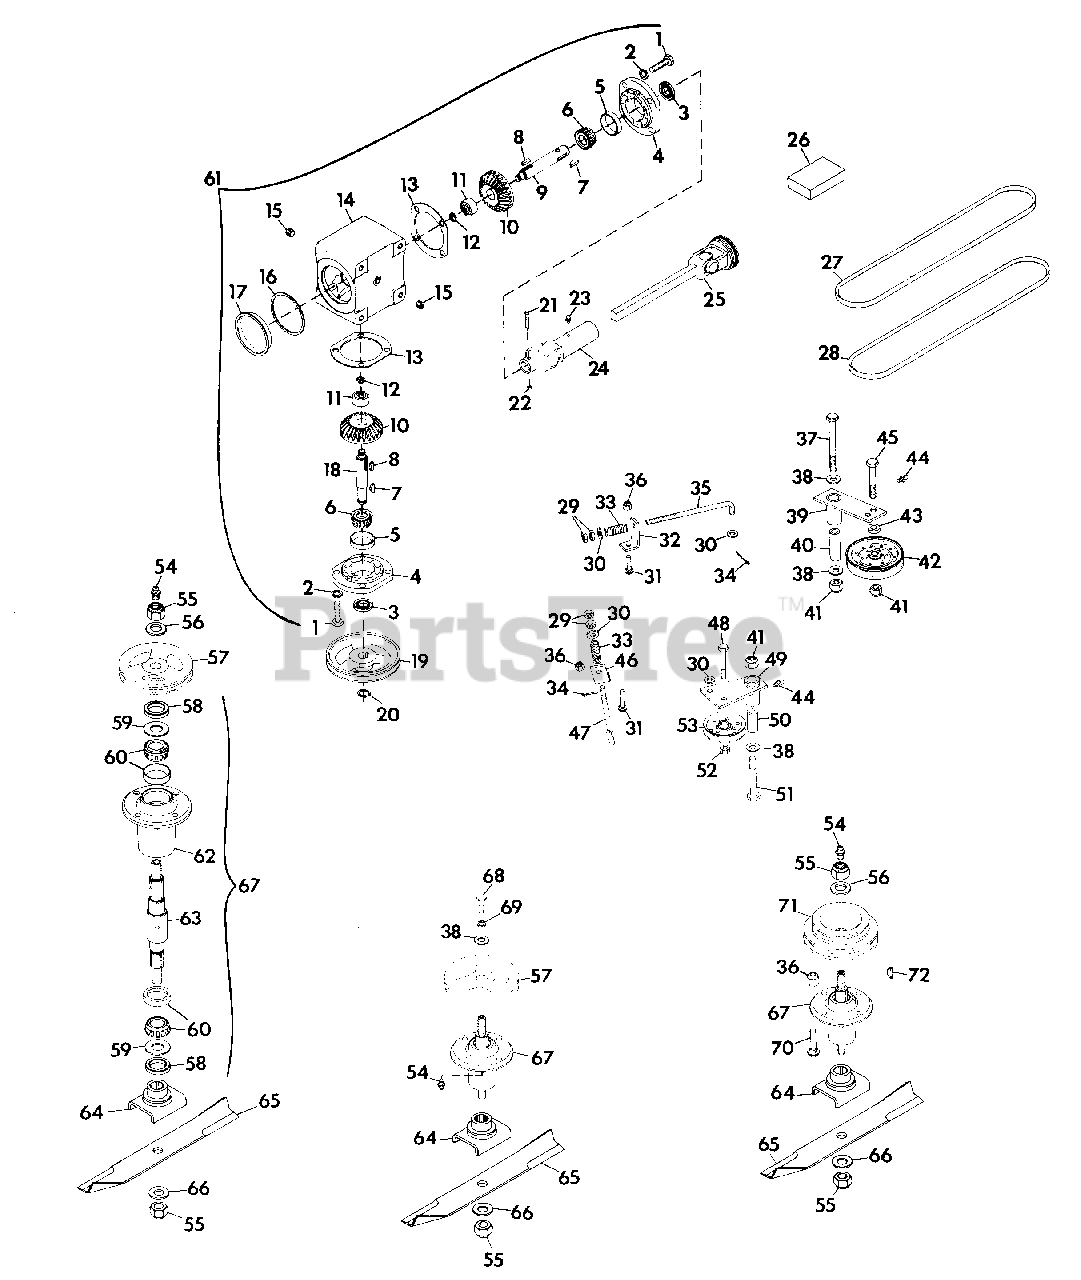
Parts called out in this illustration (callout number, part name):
1	BOLT, HEX 5/16-18X1.00
2	WASHER, LOCK 5/16 REG
3	SEAL
4	COVER
5	CUP, BEARING
6	CONE, BEARING
7	KEY, WOODRUFF .250X.875 HRD #A
8	KEY, SQUARE
9	SHAFT
10	GEAR, 1:1
11	BEARING SET
12	RING, RETAINING
13	SHIM
14	CASE
15	PLUG, PIPE
16	GASKET
17	PLATE, COVER
18	SHAFT
19	PULLEY, GEARBOX
20	RING, RETAINING .875 SHAFT
21	BOLT, HEX 5/16-18X2.25
22	NUT, LOCK 5/16-18
23	FITTING, LUBE 1/4-28
24	ASM, U-JOINT
25	SHAFT, PROP. SQ. BAR
26	KIT, REPAIR UNIVERSAL SHAFT
27	BELT, "A"
28	BELT, "B"
29	NUT, HEX 3/8-24
30	WASHER, FLAT .406X.812X.065
31	BOLT, HEX 3/8-16X1.00
32	SUPPORT, SPRING "B"
33	SPRING, COMPRESSION
34	PIN, COTTER 1/16X1.00
35	ROD, IDLER
36	NUT, LOCK 3/8-16
37	BOLT, HEX 1/2-13X3.75
38	WASHER, FLAT .500X1.250X.083
39	WELDMENT, IDLER PIVOT "B"
40	SPACER, .850X.546X2.50
41	NUT, LOCK 1/2-13
42	PULLEY, FLAT IDLER
43	SPACER, .516X.875X.300
44	FITTING, LUBE 1/4-28
45	BOLT, HEX 1/2-13X2.00
46	SUPPORT, SPRING "A"
47	ROD, IDLER
48	BOLT, HEX 3/8-16X1.75
49	WELDMENT, IDLER PIVOT "A"
50	SPACER, .850X.546X2.18
51	BOLT, 1/2-13X3.50 RD HD SQ NK
52	NUT, LOCK 3/8-16
53	SHEAVE, IDLER
54	FITTING, LUBE 1/8
55	NUT, LOCK 5/8-11
56	WASHER, FLAT .687X1.312X.122
57	PULLEY
58	SEAL, STEEL(CENTER & RIGHT SPINDLE)
58	SEAL, STEEL(LEFT SPINDLE)
59	WASHER, FLAT .975X1.970X.030(CENTER & RIGHTSPINDLE)
59	WASHER, FLAT .975X1.970X.030(LEFT SPINDLE)
60	ASSEMBLY, BEARING
61	BOX, GEAR RIGHT ANGLE
62	HOUSING, BEARING MOWER(CENTER SPINDLE)
62	HOUSING, BEARING(LEFT & RIGHT SPINDLE)
63	SHAFT, SPINDLE(RIGHT)
63	SHAFT, SPINDLE(CENTER)
63	SHAFT, SPINDLE(LEFT)
64	WELDMENT, BLADE CRADLE
65	BLADE
66	WASHER, FLAT .656X1.312X.095
67	ASM, SPINDLE(RIGHT)
67	ASM, SPINDLE(CENTER)
67	ASM, SPINDLE(LEFT)
68	BOLT, HEX SPEC. 1/2-13X1.34
69	WASHER, LOCK 1/2 REG.
70	BOLT, 3/8-16X1.375 RD HD SQ NK
71	PULLEY, DRIVE
72	KEY, WOODRUFF
